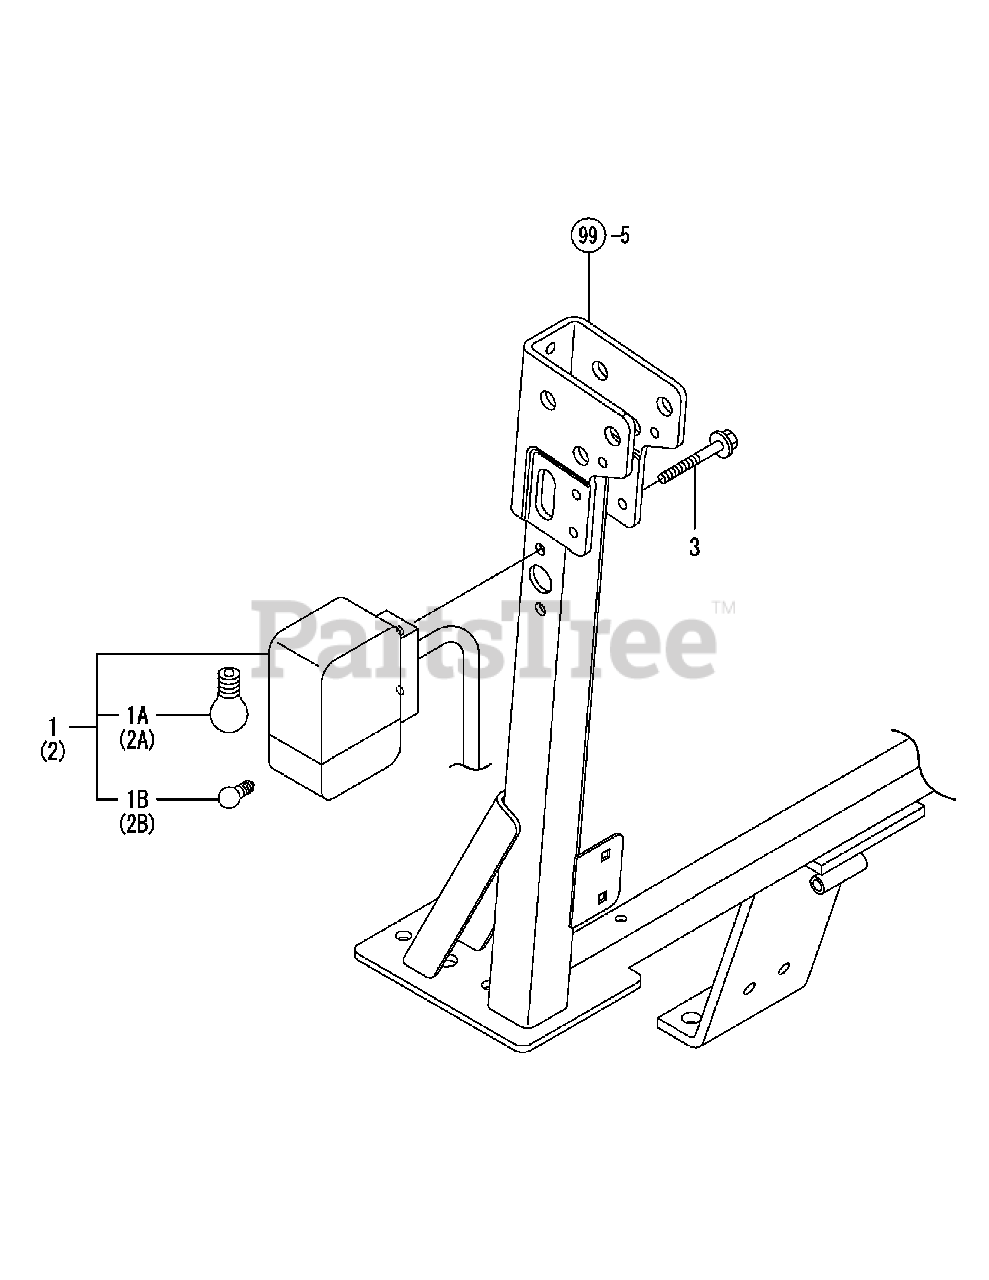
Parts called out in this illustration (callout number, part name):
1	Lamp, Warning L
1A	Bulb, 27w-12.8v
1B	Bulb, 4.9w-12.8v
2	Lamp, Warning R
2A	Bulb, 27w-12.8v
2B	Bulb, 4.9w-12.8v
3	Bolt M 8X 70 Plated
